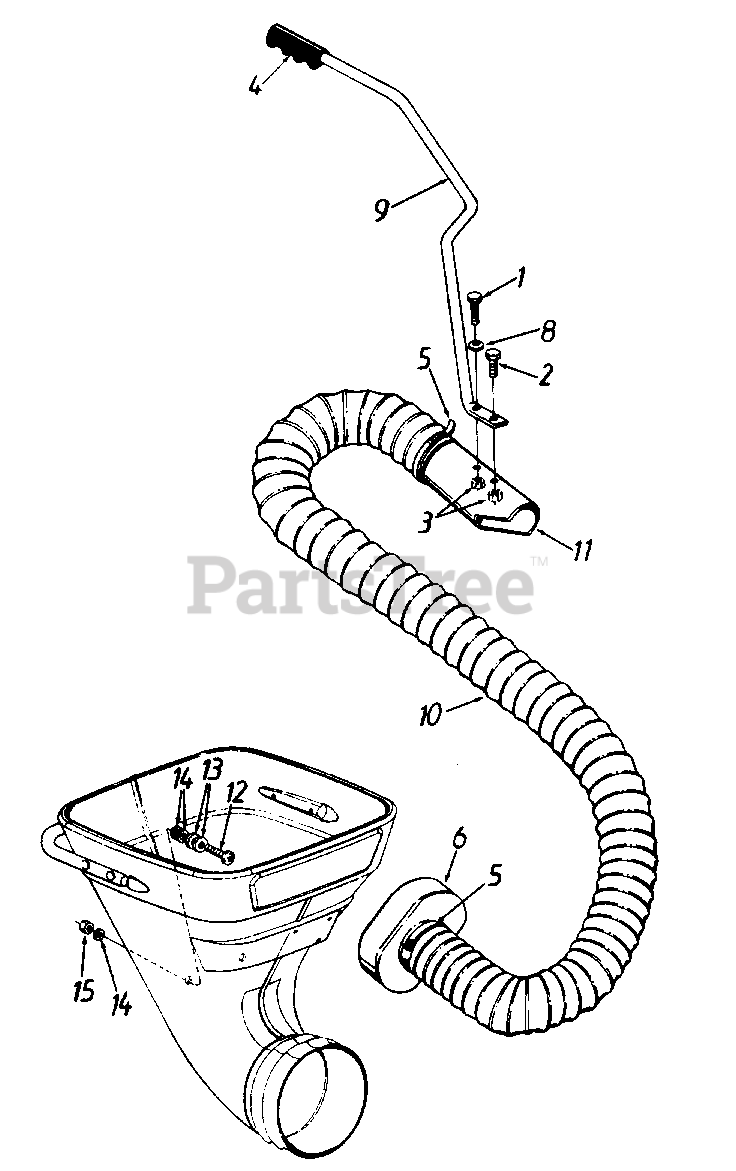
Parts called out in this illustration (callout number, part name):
1	Hex Bolt 1/4-20 x 1.25" Lg.
2	Hex Bolt 1/4-20 x .62" Lg.
3	Hex L-Nut 1/4-20 Thd.
5	Adj. Hose Clamp 5" Dia.
8	Saddle Washer .32" I.D. x .937"
10	Hose - 5" Dia.
11	Nozzle Tube
12	Truss Mach. Scr. 5/16-18 x 3/4" Lg.
13	FL-Wash. .344" I.D. x .75" O.D.
14	FL-Wash. .328" I.D. x .68" O.D.
15	Hex L-Nut 5/16-18 Thd.
